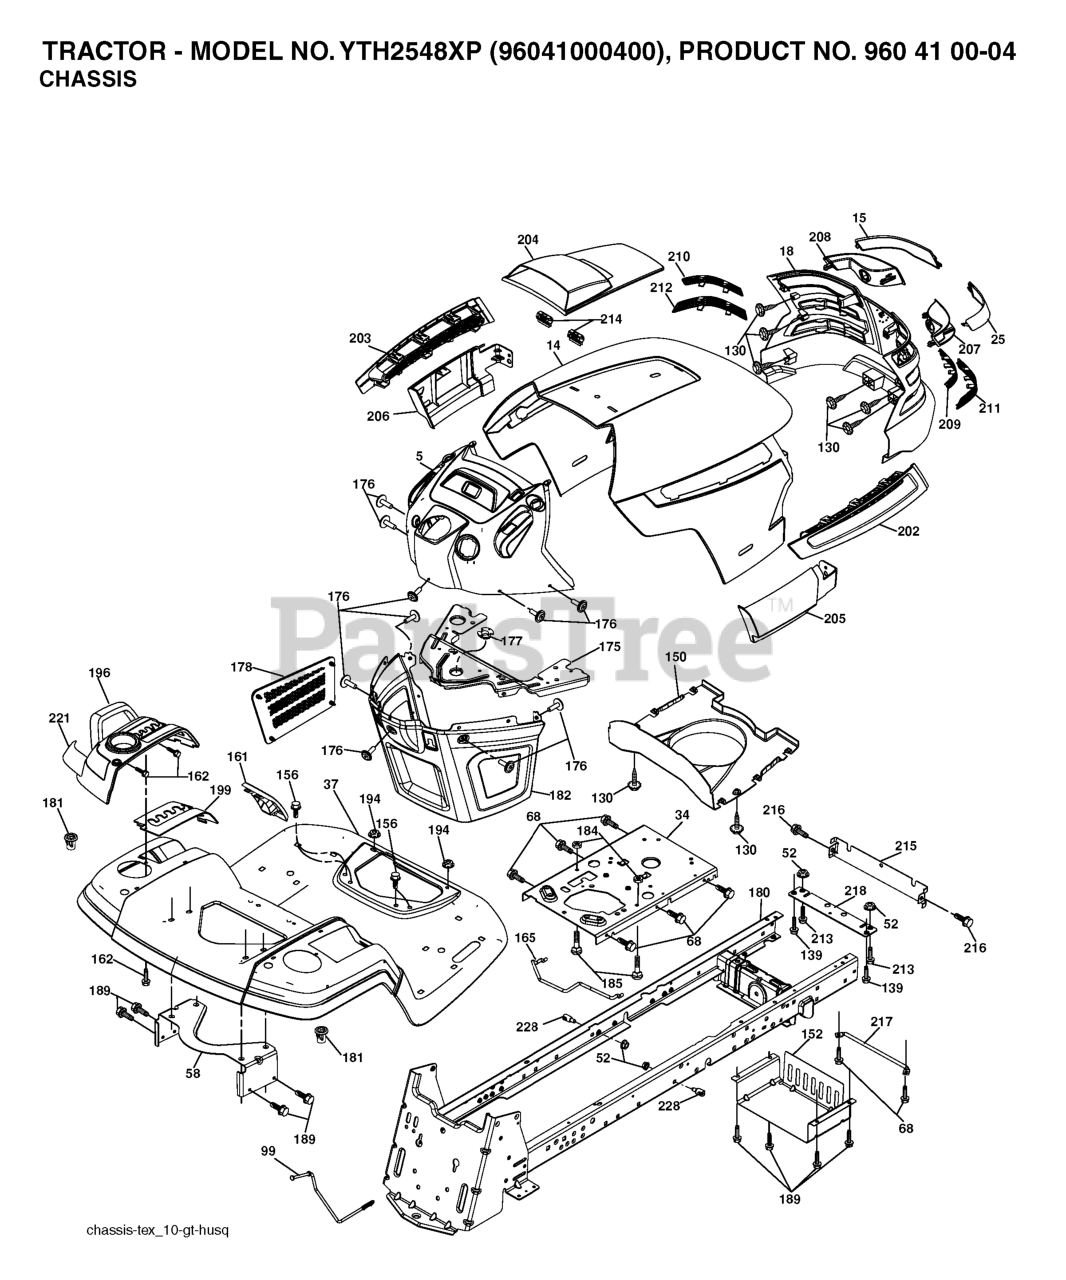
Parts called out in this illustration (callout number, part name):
5	DASH.HUSQ.UPR.ELE.SVMD
14	HOOD.PNT.HUSQVARNA.GT.
15	LENS.LH.TEX.GT.HUSQ.CL
18	GRILLE.ASM.TEX.GT.HUSQ
25	LENS.RH.TEX.GT.HUSQ.CL
34	PLATE.ENGINE.WELDED.CHASSIS
37	FENDER.PNT.TX.GT.CH/FW.ORANGE
52	LOCKNUT
58	BRKT.SUPPORT.FNDR/TANK
68	Screw 5/16-18 x 1/2 Hex, Self Tapping 5/16-18 x 1/2
99	ROD.ASM.BYPASS.0610.FE
130	SCREW
139	BOLT, SHOULDER 5/16-18
150	AIR.DUCT.HOOD.TEX.GT.HUSQ
152	SHIELD.BROWNING.WTEXLT
156	SCREW
161	CONSOLE.FUEL.WINDOW.HU
162	SCREW.HI-LO.CONSOLE
165	SUPPORT.TANK.REAR.W/TEX
175	PLATE.CROSSMEMBER.HUSQ
176	SCREW.#10-24X5/8.RN.QU
177	BUSHING, STEERING
178	CARGO.ASM.NET.TXGT.W/C
180	CHASSIS.WLDMT.TX.GT.05
181	BUSHING.MNT.FEND.CRGO.
182	DASH.LOWER.COMMON.12V.
184	SPACER.FENDER
185	BOLT.CARRIAGE.5/16-18
189	SCREW
194	NUT LOCK HEX FLANGE 5/16-18
196	RP CONSOLE.ASM.DECKLFT.W/
199	PLATE.DECK.LIFT.HUSQVARNA.GT
202	VENT.SIDE.HOOD.HUSQ.RH.GREY
203	VENT.SIDE.HOOD.HUSQ.LH.GRAY
204	VENT.TOP.HOOD.HUSQVARN
205	SKIRT.HOOD.SIDE.HUSQ.RH.GREY
206	SKIRT.HOOD.SIDE.HUSQ.LH.GREY
207	BEZEL.RH.TEX.GT.HUSQ
208	BEZEL.LH.TEX.GT.HUSQ
209	INSERT.HEX.GRILL.HUSQ.GREY
210	INSERT.HEX.GRILL.HUSQ.
211	INSERT.HEX.GRILL.HUSQ.
212	INSERT.HEX.GRILL.HUSQ.
213	BOLT
214	CLIP.RETAINER.TINNER.
215	COVER.CHASSIS.FRONT.WE
216	SCREW, 5/16-18 X 1/2
217	ROD PIVOT CHASSIS/HOOD
218	X-PIECE.HOOD.STOP.NON/
221	REFLECTOR.LH.TEX GT HU
228	STUD.FASTNER.W/ANTI-ROTATE
